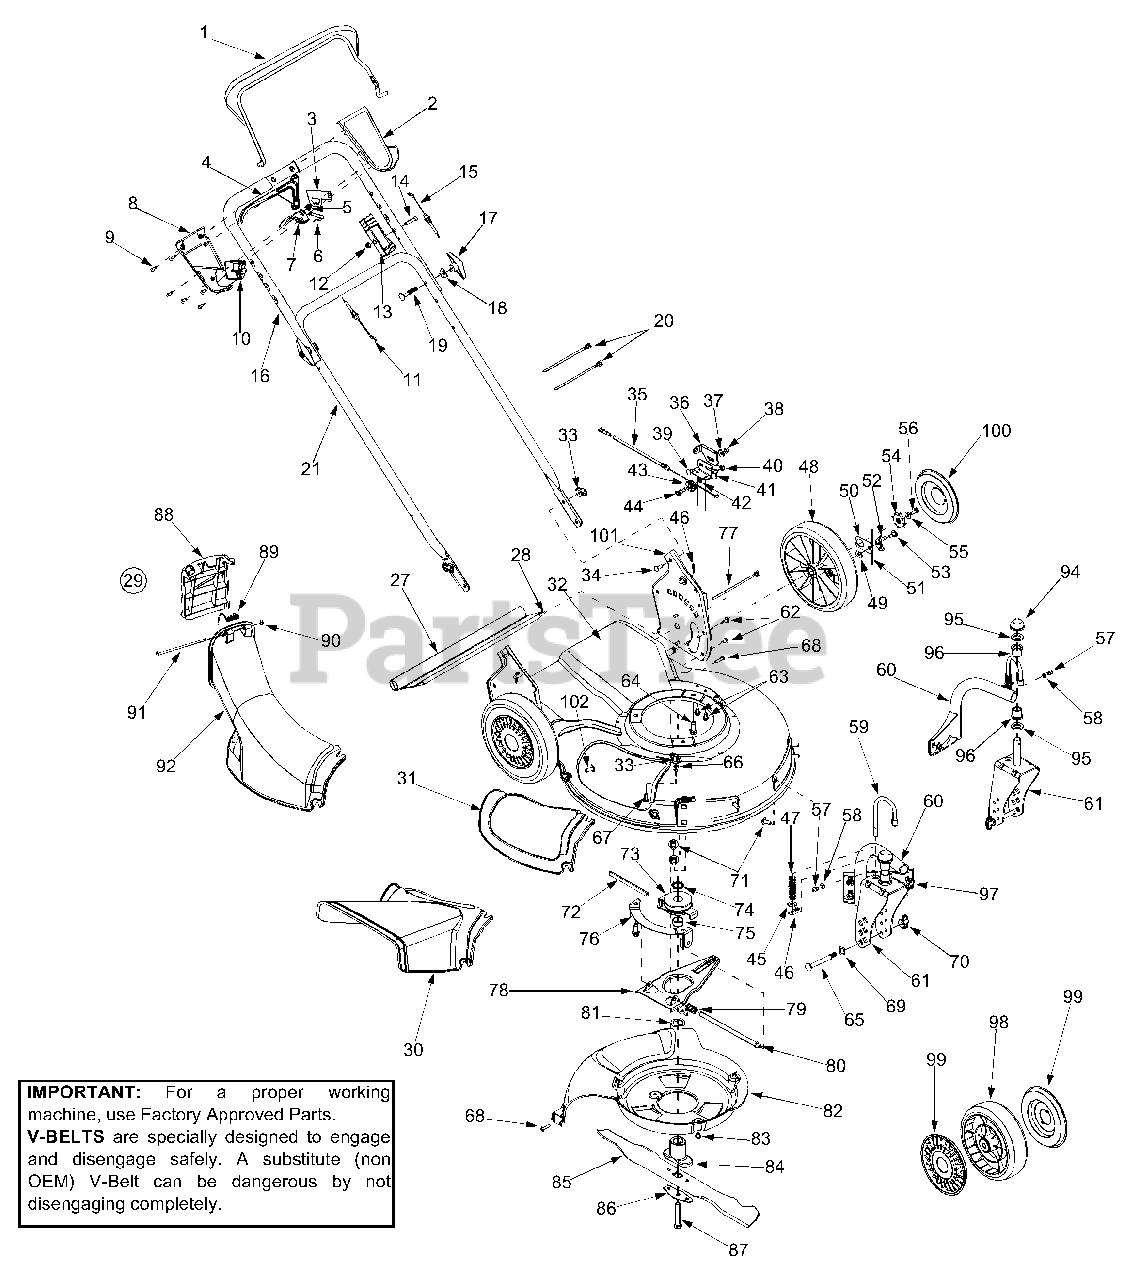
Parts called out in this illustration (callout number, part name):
1	Control Handle
2	Upper Control Housing
3	6 Spd. Rack Cable Bracket
4	Control Lever
5	Gear Insert
6	Shift Lever Spring
7	6 Speed Shift Lever
8	Lower Control Housing
9	C Sunk Tap Screw #10 x.75 Lg
10	Cable Mounting Cap
11	Drive Cable 51.0
12	Top Lock Nut 1/4-20
13	Control Housing
14	Oval C-Sunk Screw
15	Control Cable 47"
18	Saddle Washer.320 ID x.830 OD
19	Carriage Bolt 5/16-18 x 2.0
20	Cable Tie
27	Trail Shield
28	Trail Shield Wire
29	Chute Assembly
30	Side-Discharge Chute
31	Mulch Cover
34	Carriage Bolt 1/4-20 x.75
35	6 Speed Cable
38	Hex Nut 1/4-20
39	Carriage Screw 1/4-20 x.50
40	Hex Nut 1/4-28
43	Cable Roller
44	Shoulder Screw.375 ID x 1/4-14
45	Flat Washer.330 ID x.630 OD
46	Cotter Pin
47	Compression Spring
48	Wheel 9 x 2.125
49	Top Lock Tab Weld Nut 1/4-20
50	Ratchet Pawl Plate
51	Plastic Spring Ratchet
53	Shld Screw.340 ID x.285 OD
54	Wheel Rachet
55	Bell Washer.265 ID x.75 OD
56	Hex Cap Screw 1/4-20 x.620
57	Grease Fitting
58	Flat Washer.203 ID x.403 OD
59	Wheel Pin Lock
62	Screw 1/4-14 x.500
63	Screw 1/4-20 x.625
64	Hex Washer Screw 3/8-16 x 1.0
65	Caster Axle
66	Push Nut.25ID x.50OD
67	Carriage Screw 1/4-20 x.75
68	Screw #12-16 x 1.00
69	Wave Washer.531 ID x.781 OD
70	Wing Nut
71	Carriage Bolt 5/16-18 x.62
72	Belt 3/8 x 39.24
73	Pulley Assembly
74	Sleeve Spacer.88 ID x 1.13 OD
75	Sleeve Spacer.88 ID x 1.00 OD
77	Cable Tie
80	Pivot Shaft
81	Wave Washer 1.38 ID x.88 OD
82	Baffle
83	Screw 1/4-20 x 3.75
84	Blade Adapter
85	21" Mulching Blade
86	Blade Bell Support
87	Hex Bolt 3/8-24 x 2.5
88	Chute Door
89	Torsion Spring
91	Pivot Rod
92	Discharge Chute
95	Flat Washer.640 ID x 1.12 OD
96	Flange Bearing
97	Flange Lock Nut 5/16-18
98	Wheel 7 x 2
99	Hubcap - Spoke w/ Hole
100	Hubcap - Radial Spoke
